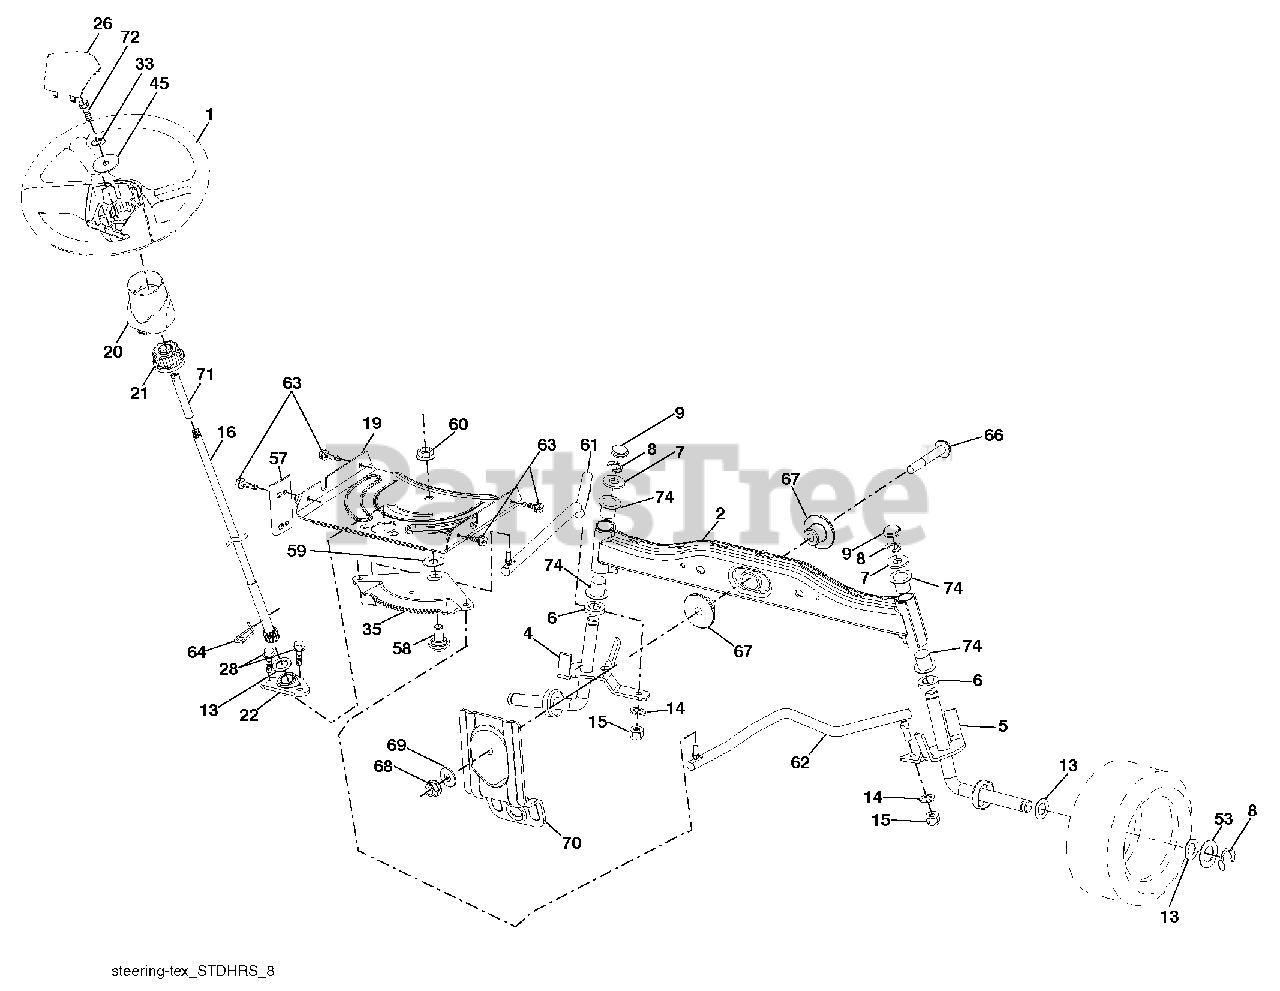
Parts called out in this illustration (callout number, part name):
1	Wheel, Steering Husq SR
2	Axle Asm., Front
4	Spindle Asm., LH
5	Spindle Asm., RH
6	Bearing, Race Thrust Hardened
7	Washer 25/32 x 1-5/8 x 16 Ga.
8	Ring, Klip #T5304-75
9	Cap, Spindle
13	Washer, 25/32 x 1-1/4 x 16 Ga.
14	Washer, Lock Hvy Hlcl Spr 3/8
15	Nut, Crown Lock 3/8-24 unf
16	Shaft Steering
19	Plate Steering
20	Boot, Steering
21	Adapter, Wheel Steering
22	Strg. Supt. Lower
26	Insert, Wheel Steering Husq SR
28	Screw 3/8-16 x 3/4
33	Washer Lock 5/16
35	Gear, Sector Plate
45	Washer 11/32 x 2-3/8 x 12 Ga.
53	Washer Hardened .793 x 1.637 x .060
57	Bracket Upstop
58	Bolt Shoulder Sector Pivot CFM
59	Washer Thrust Sector Steering
60	Nut Flange Lock 5/8-11
61	Draglink, LH
62	Draglink, RH
63	Screw 5/16-18 x 3/4
64	Retainer Clip Spring Steering
66	Bolt Hex Fghd 7/16-14 x 3 Serr
67	Bushing PM Front Axle
68	Nut Lock Flange 7/16-14 Gr. 5
69	Washer 1.5 x .505 x .118
70	Bracket Deck Susp. Front
71	Shaft Extension Steering
72	Bolt Fin. Hx. 5/16-18 x 4 w/Patch
74	Bearing
